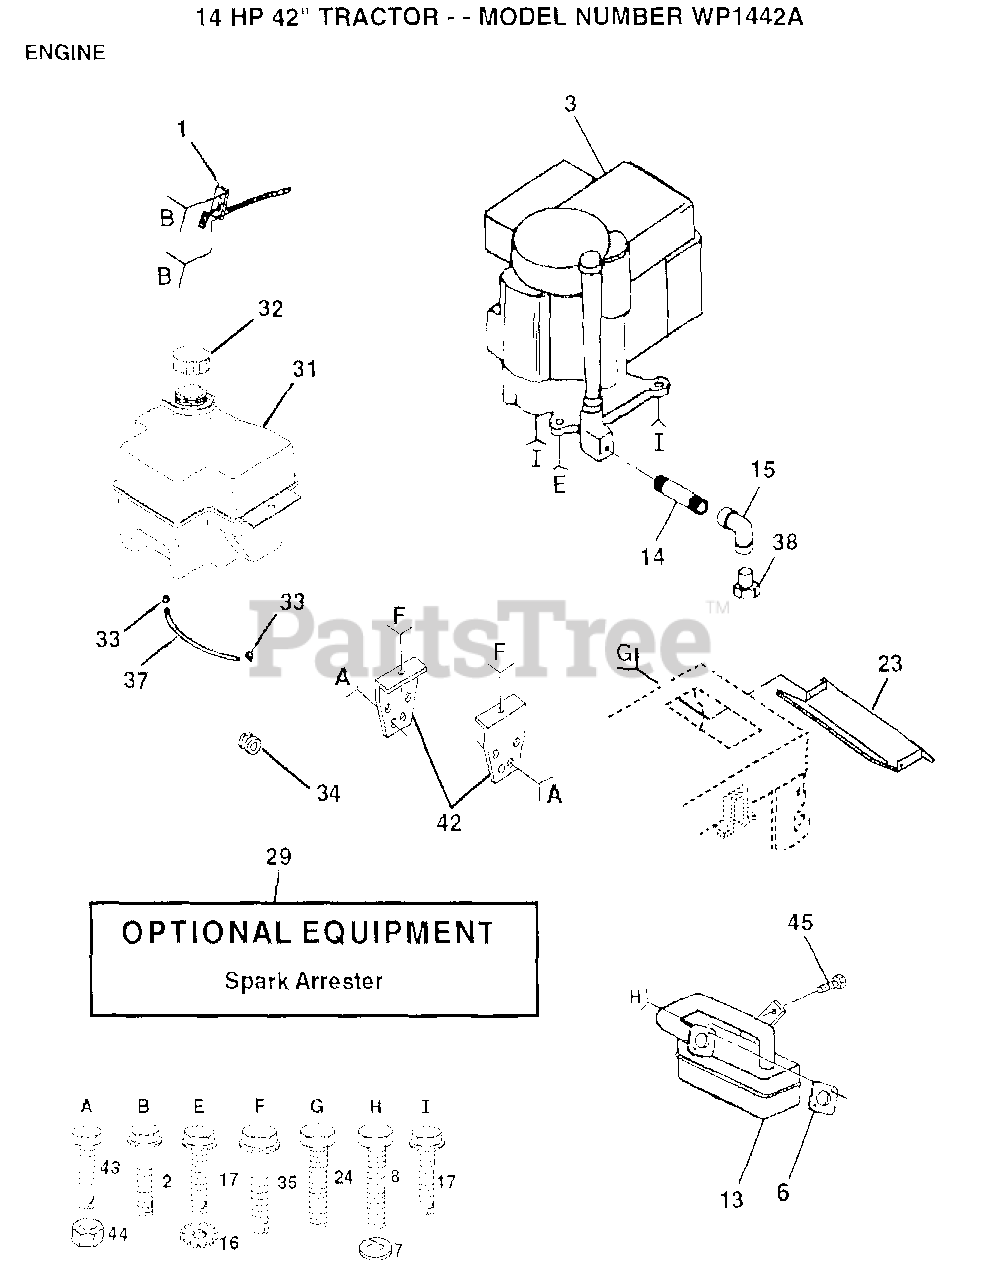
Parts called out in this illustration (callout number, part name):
1	"CONTROL,THROTTLE"
2	SCREW LT
7	LOCKWASHER
8	SCREW
13	MUFFLER
14	PIPE NIPPLE
15	ELBOW
16	LOCKWASHER.5/16.E
17	SCREW
24	SCREW
32	CAP ASM FUEL
33	HOSE CLAMP
35	SCREW
37	LINE FUEL
42	BRACKET.SUPT.TANK
43	BOLT
44	NUT
45	SCREW HEX CRT
